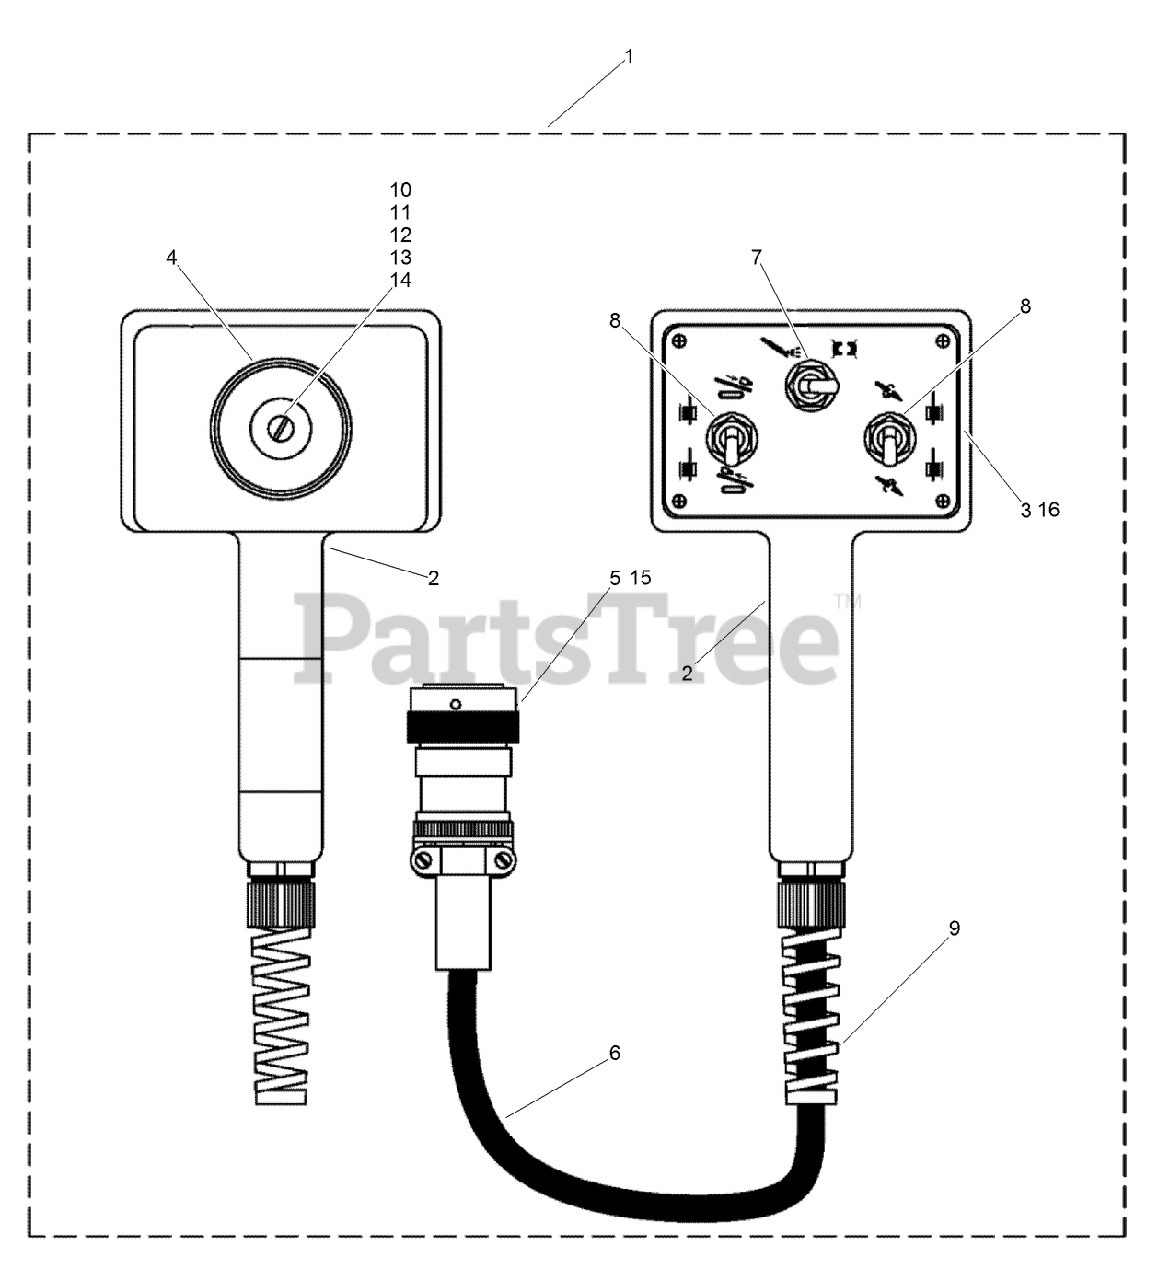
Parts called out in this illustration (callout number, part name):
1	CONTROL - Life Jacket
2	HOUSING - Pendant
3	PLATE - Mounting, Life Jacket
4	MAGNET - Ceramic, 2.03 Diameter x .312 H
5	PLUG - Female, with Clamp, 18-14
6	CABLE - Type SDN, 18/10, 6 Feet
7	SWITCH - Toggle, SPDT, On-Off-On, Seal
8	SWITCH - Toggle, SPDT, (On)-Off-(On), Seal
9	CORD GRIP - With Spiral, .24-.47, Black
10	NUT - Hex, #10-32, 303 Stainless Steel
11	WASHER - Flat, #10, 303 Stainless Steel
12	WASHER - Flat, 1/4 inch Stainless Steel
13	WASHER - Lock, Split Type, No. 10
14	SCREW - Machine, Slotted Pan Head
15	SOCKET - Connector, SZ 16-18
